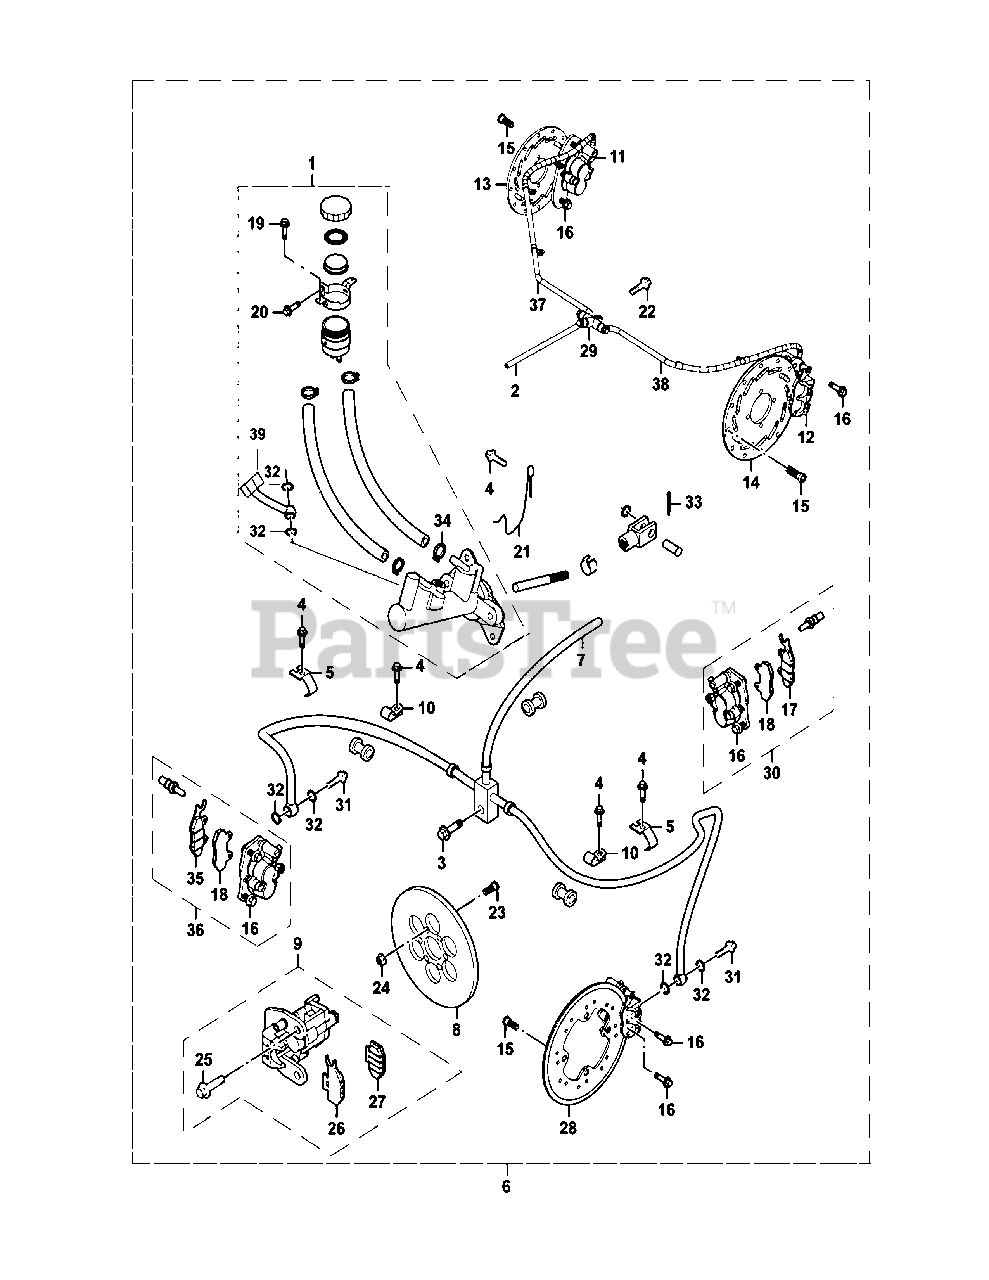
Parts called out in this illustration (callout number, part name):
1	Rear Brake Pump
2	Rear Brake Oil Pipe
3	Hexagon Flange Bolt M6×25
4	Hexagon Flange Bolt M6×12
5	Oil Pipe Clip, Front Disc Brake
6	Disc Brake Parts
7	Front Brake Hose
8	Braking Plate
9	Middle Brake
11	Rear Right Brake Caliper
12	Rear Left Brake Caliper
13	Rear Right Brake Plate
14	Rear Left Brake Plate
15	Bolt M8×15-15×5
16	Bolt M10×1.25×22
17	Outer Brake Pad Assy (Front & Left)
18	Inner Brake Pad Assy
19	Hexagon Flange Bolt M6×16
20	Hexagon Flange Bolt M6×20
21	Oil Pipe Orientated Spring
22	Hexagon Flange Bolt M6×30
23	Hexagon Step Bolt M6×14-7×15
24	Hexagon Flange Self-Lock Nuts M6
25	Hexagon Bolt M10×1.25×55
26	Outer Brake Pad
27	Inner Brake Pad Assy
28	Front Brake Pad
29	Rear Triplet Joint
30	Front Left Brake Caliper
31	Strainer Bolt
34	Oil Pipe Hoop
35	Outer Brake Pad Assy (Front & Right)
36	Front Right Brake Caliper
37	Rear right Brake Hose
38	Rear left Brake Hose
39	Brake Switch
